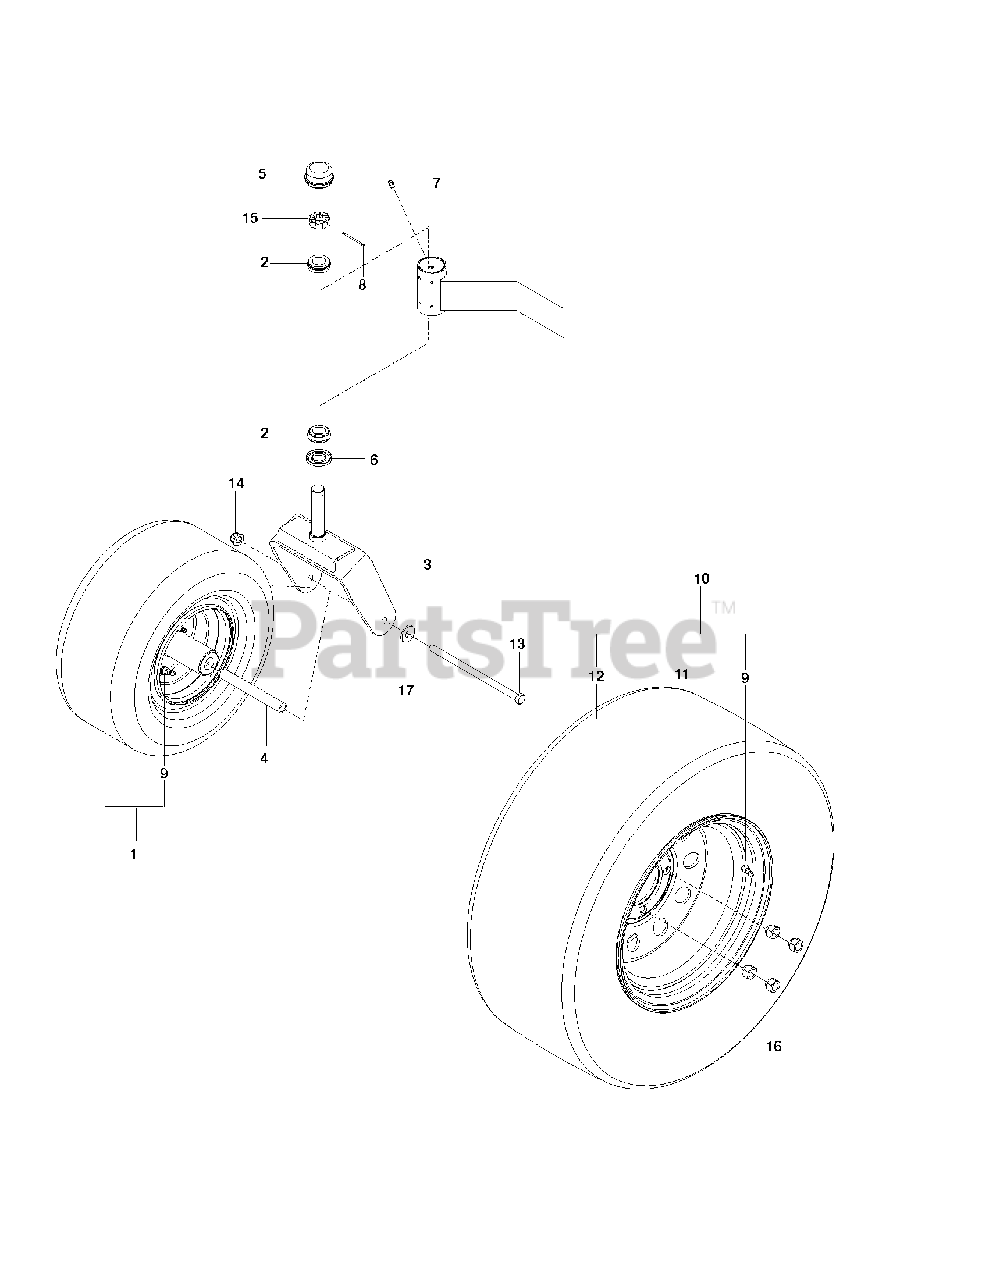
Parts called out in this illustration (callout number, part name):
1	ASM, TIRE
2	TAPERED ROLLER BRG
3	YOKE, CASTER, BLUE
4	SPACER, PIVOT
5	GREASE CAP
9	VALVE STEM TR-412
10	ASSEMBLY, TIRE 23 X 9.20-12
11	RIM 12X7, 1.5" NEG OFFSET
12	TIRE, 23 X 9.50-12
13	HEX SCREW 1/2-13 X 9.5 GR5
14	NUT, 1/2-13 HEX FLG NYLOC ZD
15	NUT 1"C HEX SLOTTED
16	LUG NUT 1/2F
17	WASH USS FLAT 1/2
